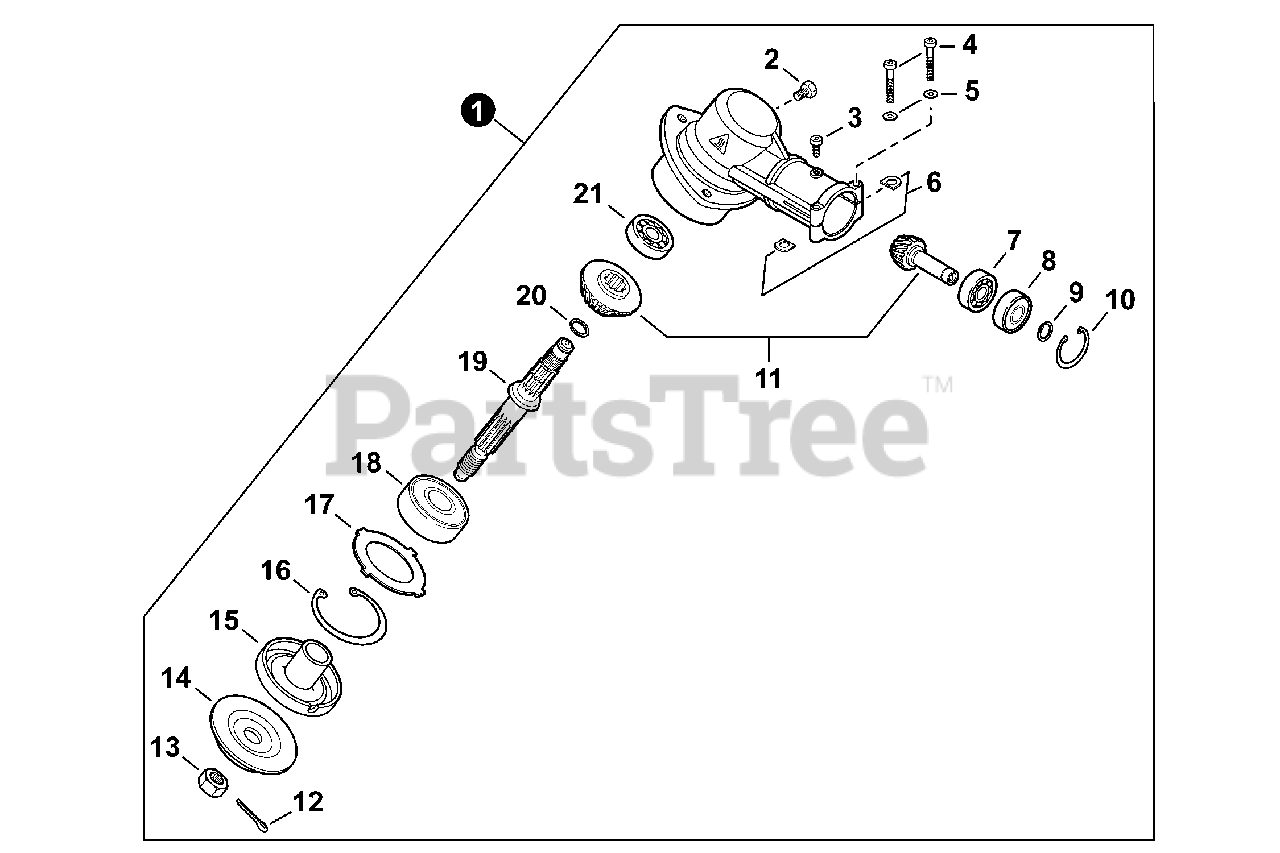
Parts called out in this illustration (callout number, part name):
1	GEAR CASE ASSY
2	BOLT M8×1.25
3	BOLT, TORX 5×10
4	BOLT 5×35
5	WASHER, FLAT 5.5×10×0.8
6	D-WASHER
7	BEARING, BALL 6900
8	BEARING, BALL 6900-Z
9	RING, SNAP 10
10	RING, SNAP 22
11	GEAR SET
12	PIN, COTTER 2×22
14	PLATE, ADAPTOR - LOWER
15	PLATE, ADAPTOR - UPPER
16	RING, SNAP 32
18	BEARING, BALL 6201
19	SHAFT, GEAR
20	RING, SNAP 12
21	BEARING, BALL 609
